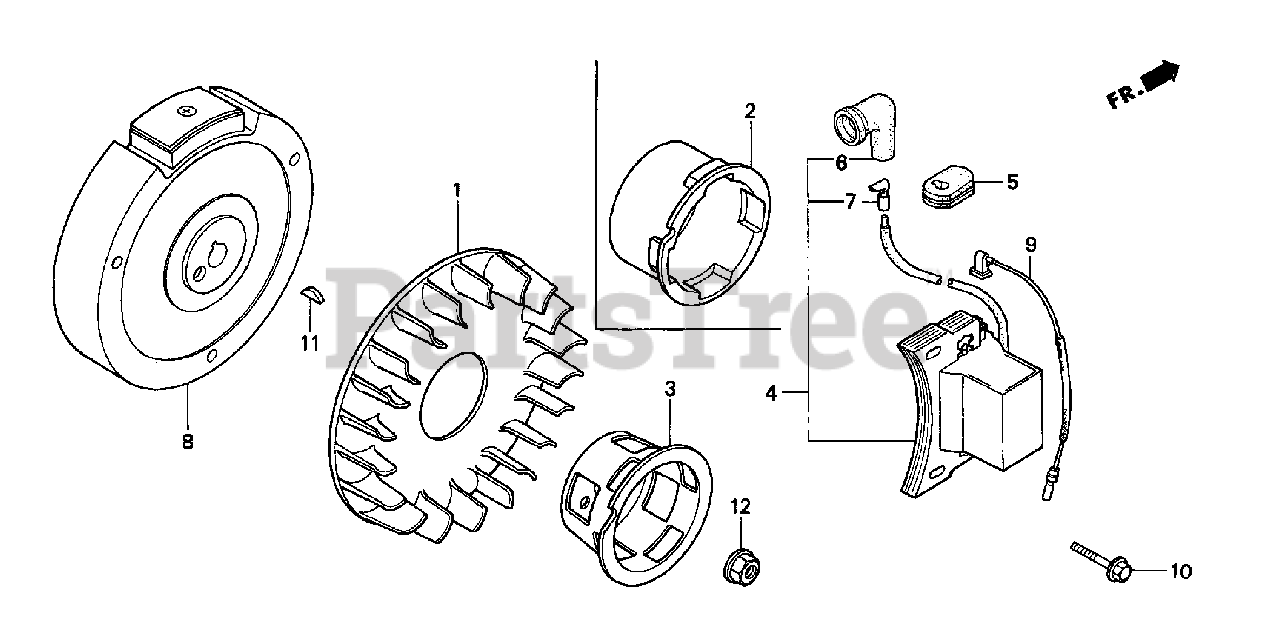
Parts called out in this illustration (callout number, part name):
1	FAN, COOLING
2	PULLEY, STARTER
3	PULLEY, STARTER
4	COIL ASSY., IGNITION
5	GROMMET, IGNITION WIRE
6	CAP, IGNITION (TOYO)
7	TERMINAL, PLUG
8	FLYWHEEL
9	WIRE, STOP SWITCH
10	BOLT, FLANGE (6X25)
11	KEY, WOODRUFF (3MM)
12	NUT, FLANGE (12MM)
